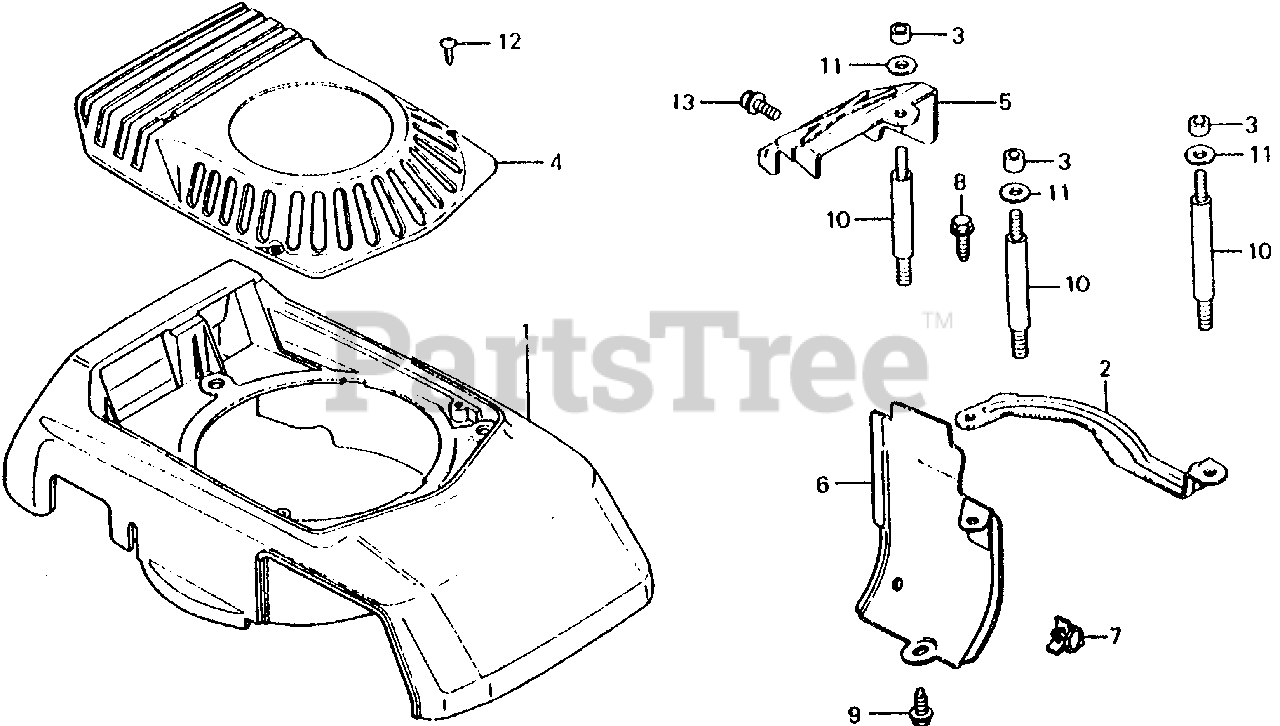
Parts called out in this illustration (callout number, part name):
1	COVER, FAN *R8* (BRIGHT RED)
2	PLATE, SIDE
3	COLLAR, FAN COVER
4	HOOD, FAN COVER *NH31* (MCKINLEY WHITE)
5	PLATE, GUIDE
7	CLIP, IGNITION WIRE (8MM)
8	BOLT, FLANGE (5X12)
9	BOLT, FLANGE (6X12) (CT200)
10	BOLT, SPECIAL STUD
10	BOLT, SPECIAL STUD (NOT AVAILABLE)
11	WASHER (6MM)
11	WASHER, PLAIN (5MM)
12	SCREW, TAPPING (4X12)
13	BOLT, FLANGE (6X12)
